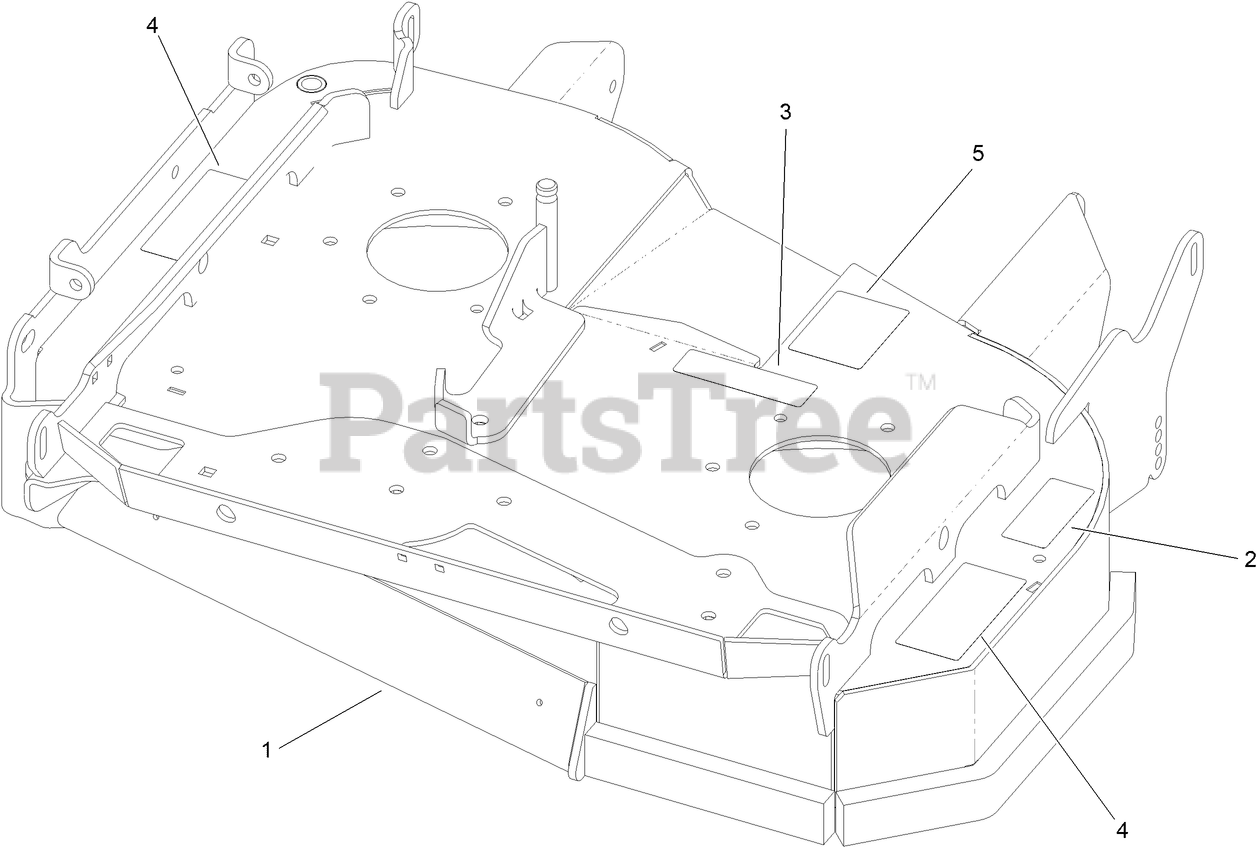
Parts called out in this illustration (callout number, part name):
1	ASM-DECK W/DECALS
2	DECAL-BOLT TORQUE
3	DECAL-COVER, MISSING
4	DECAL-WARNING THROWN OBJECT
5	DECAL-BELT ROUTING
